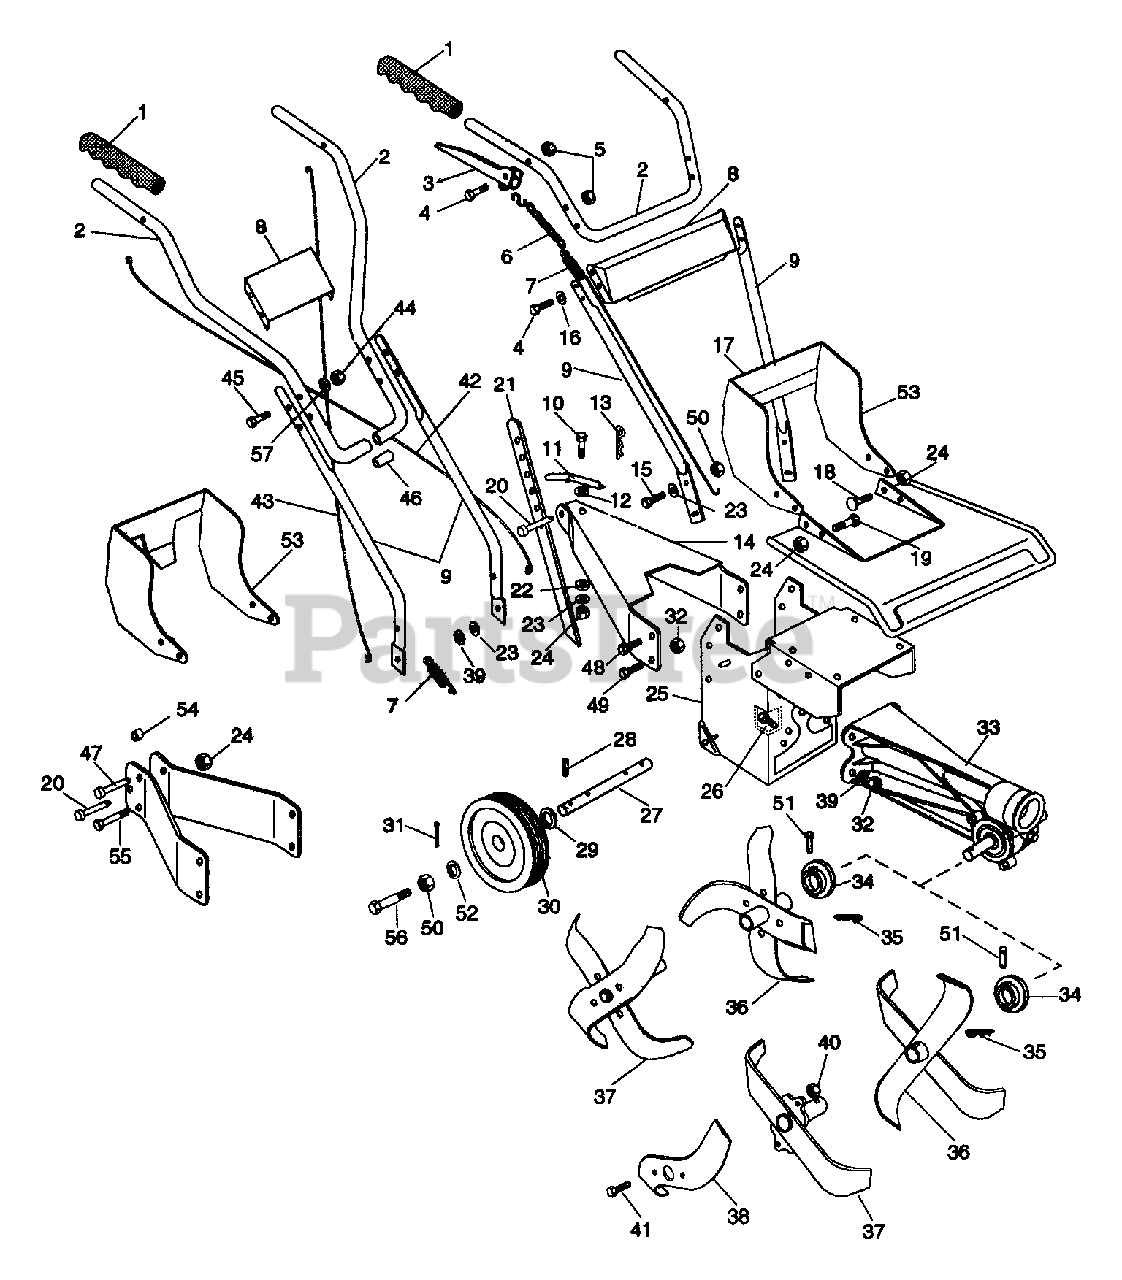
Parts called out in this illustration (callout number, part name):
1	GRIP
1	HANDLE GRIP- BLACK PVC-SM1217
2	RIGHT UPPER HANDLEBAR
2	LEFT UPPER HANDLEBAR
2	HANDLEBAR
3	CLUTCH HANDLE
3	Clutch Handle
4	BLT-HEX .25-20X1.50 PL GR5
5	NUT-LK-CTR .250-20 PL
6	CLUTCH CHAIN
6	Clutch Chain
7	SG-TENS .080X.25X31.6 WLD 35
7	SG-TENS .092X.69X1.75 WLD 54
8	HANDLEBAR PANEL
8	NAME PLATE
9	LOWER HANDLE BAR
9	L H LOWER HANDLEBAR
9	R H LOWER HANDLEBAR
10	BLT-HEX .31-18X.75 PL GR2
11	RETAINER CLIP
12	WAVE WASHER .515 X 1.00 X .125
13	PIN-HAIR EXT .12X.31X2.37 PL
13	PIN-HAIR INT .08X.18X1.18
14	DEPTH STICK HOLDER
15	BLT-HEX .38-16X1.00 PL
16	WSHR-FL-STL .268X.562X.046 PL
17	TINE HOOD
18	BLT-RDHDSQNK .312-18X.62SHTPL
19	BLT-HEX .31-18X.63 PL GR 2
20	CLEVIS PIN .437/.431X1.50 YWZC
20	PIN-CLEV .438X.958 PL
21	DEPTH STICK
22	SPACER BUSHING .5 X .32 X .21
23	WSHR-FL-STL .38X.875X.083 PL
24	NUT-LK .312-18 GR A PL
25	FRAME
26	BLT-HEX .38-16X1.25 PL GR 2
26	SCREW - FLG WIZ LOCK HH PL
27	AXLE ROD
28	PIN-ROLL .125X1.38
29	SPACER .76 X .51 X .56
30	WHL
30	T/WHL ASSY
31	PIN-COTR .12 X 1.25 PL
32	NUT-HEX .375-16
32	NUT-LK-FLG .375-16 PL
33	GEAR CASE - CAST IRON
33	GEAR CASE-ALUM-902806,07,08,09
34	DUST CAP
35	PIN-HAIR INT .08X.38X1.42 YWZC
36	RH INNER TINE SPOOL
36	LH INNER TINE SPOOL
36	R.H. INNER TINE SPOOL
36	L.H. INNER TINE SPOOL
37	LH OUTER TINE SPOOL
37	RH OUTER TINE SPOOL
37	R H OUTER TINE SPOOL
37	L H OUTER TINE SPOOL
38	TURBO-TINE
39	WSHR-LK .375X.115 HVY PL
40	NUT-LK-TOP .437-14 GR C PL
41	BLT-HEX .44-14X1.00 GR5
42	CLUTCH CABLE REVERSE
43	CLUTCH CABLE FORWARD
44	NUT-HEX .312-18
45	BLT-CRVD-HD .31-18X1.44 YWZC
46	HANDLEBAR INSERT
47	PIN, CLEVIS .243/.248X1.50 YWZ
48	BLT-HEX .38-16X.75 PL GR2
49	BLT-HEX .38-16X1.50 PL GR5
50	NUT-LK-CTR .375-16 GR A PL
51	CLEVIS PIN
52	WSHR-FL-STL .531X1.062X.095 PL
53	SHIELD
54	SPACER .333X.520X.340
55	BLT-HEX .31-18X.88 PL GR2
56	SHOULDER BOLT .50 X 1.51 YWZC
57	WSHR-LK .312X.097 PL HVY
